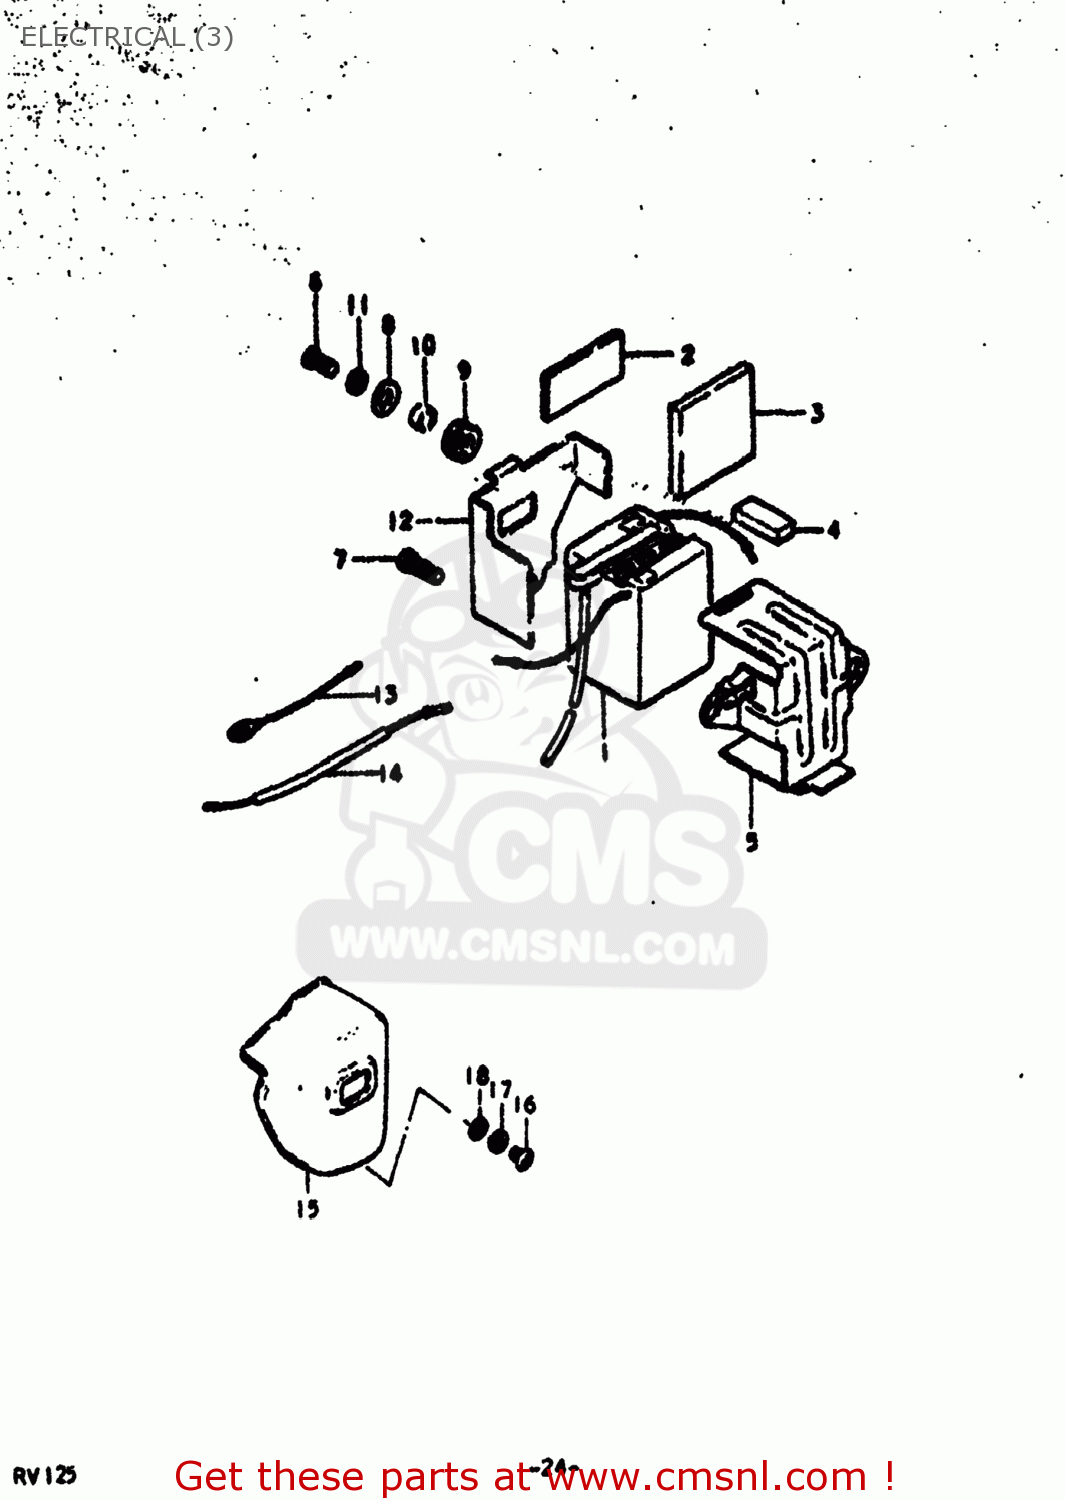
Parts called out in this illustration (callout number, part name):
1	BATTERY ASSY(6N4-2A4.2AH)
2	CUSHION,BATTERY
3	CUSHION,BATTERY
4	CUSHION 20X45X6
5	HOLDER,BATTERY
6	BOLT
7	BOLT
8	WASHER (6.5X20X1.2)
9	CUSHION
10	SPACER (7X9X7)
11	LOCK WASHER
12	BRACKET,BATTERY HOLDER
13	LEAD WIRE
14	WIRE,BATTERY LEAD
15	PLATE,BATTERY HOLDER
16	SCREW
17	LOCK WASHER
18	WASHER
